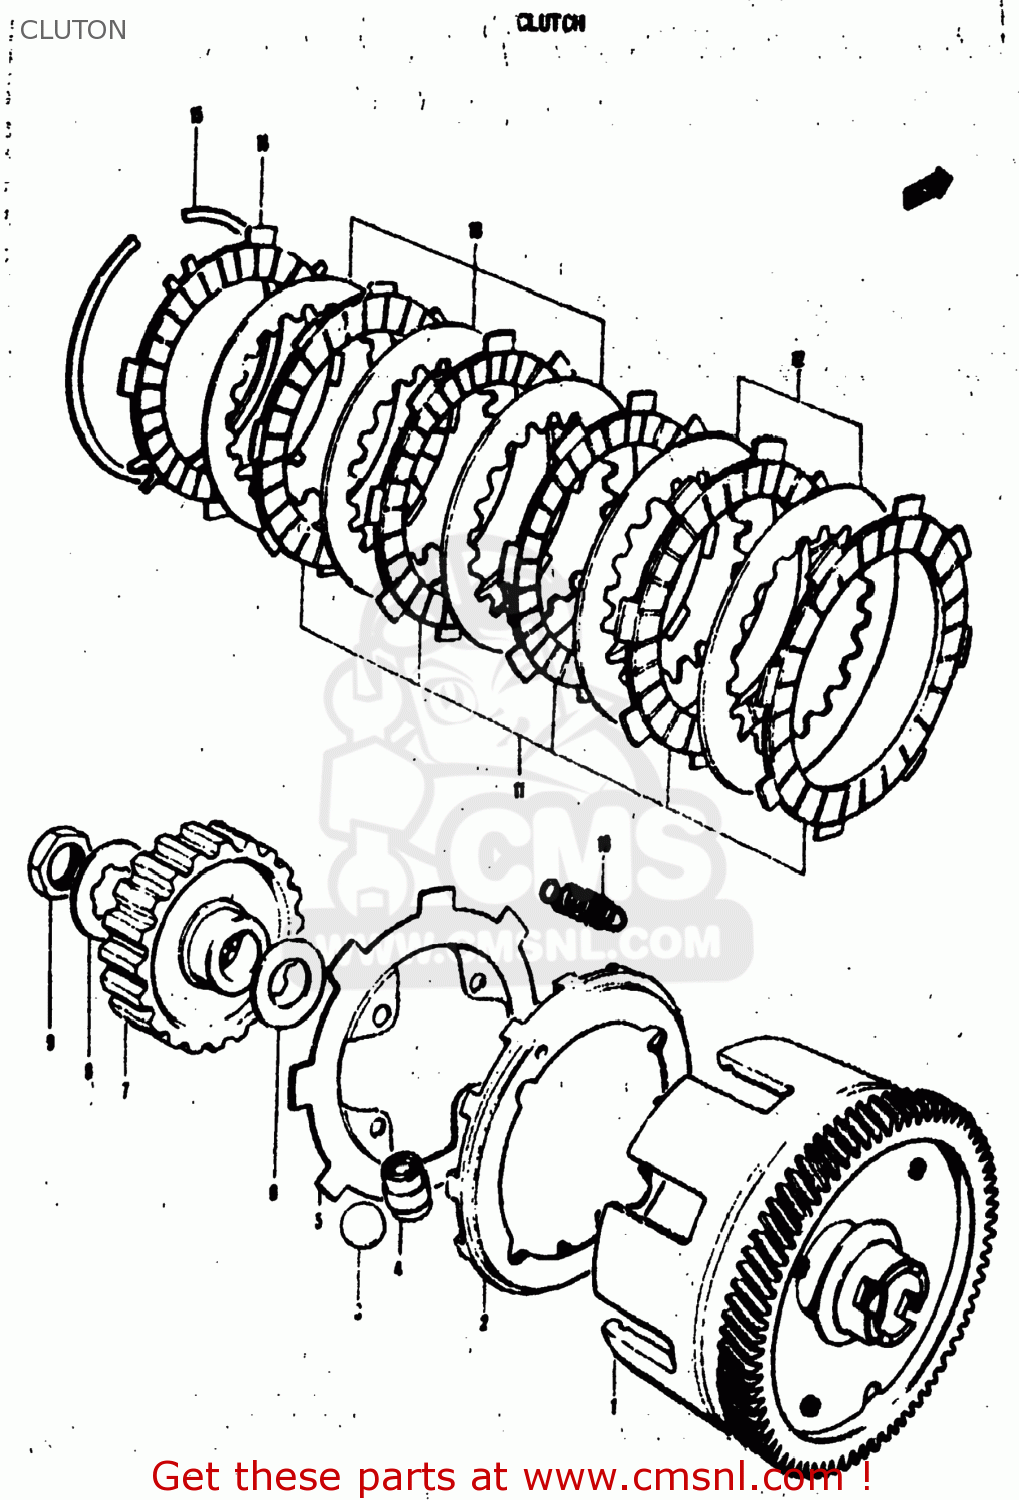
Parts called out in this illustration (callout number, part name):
2	ROLLER GUIDE RING
3	BALL
4	ROLLER,CLUTCH
5	CLUTCH INNER PLATE
6	WASHER
8	WASHER,LOCK
9	NUT
10	SPRING
11	PLATE, DRIVE (T:3) (MCA)
12	PLATE, ADJUSTER (T:1.2)
13	PLATE,CLUTCH DRIVEN(T:1.6)
14	PLATE,CLUTCH DRIVE OUTER
15	CLUTCH OUTER PLATE CIRCLIP
